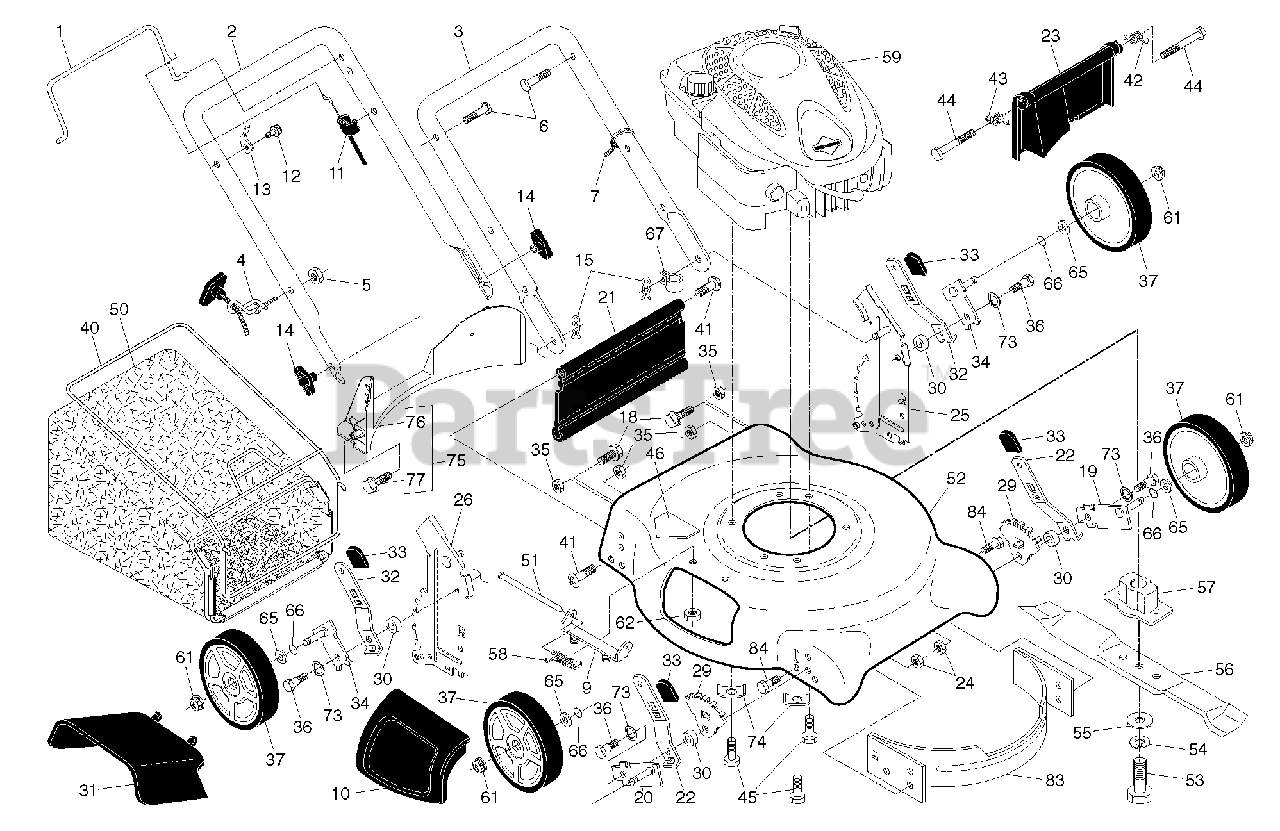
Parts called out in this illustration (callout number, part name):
1	BAIL.CONT.D.STRAIGHT.PUSH.YELL
2	HANDLE.UPPER.ECONOMY.BLACK
3	HANDLE.LOWER.D-STRAIT.BLACK
4	GUIDE.ROPE.STD.BLK.ZIN
5	NUT
6	BOLT, HANDLE 5/16-18X1.75
7	TIE GUIDE
9	BRACKET.ASM.HOUSING.EZ.MUL
10	MULCH DOOR
11	CABLE.MZR.RATO.22"LOW.
13	BRACKET.UPSTOP.RT
14	KNOB.WING.PLASTIC.BLACK
15	HAIRPIN COTTER
18	SCREW 1/4X20
19	AXLE ARM ASSY FRONT LH
20	AXLE ARM ASSY FRONT RH
21	KIT.SKIRT.21 DOMED.W/LIP
22	SELECTOR SPRING, FRONT
23	REAR DOOR ASSY
24	NUT.FLANGE.HEX.5/16X18.BLACK
25	RP BRACKET.ASM.HANDLE.LH.LW.BL
26	RP BRACKET.ASM.HANDLE.RH.LW.BL
29	WHEEL ADJ BRACKET FRONT
30	SPACER.HEIGHT.ADJUSTER
31	CLIP ON DISCHARGE GUARD
32	SPRING.SELECTOR.21RD.HTTRT.BZP
33	KNOB.ERGO.DLX.PLAS.MARI.MULTI
34	ARM.ASM.AXLE.REAR.5/9.POS.BZP
35	NUT.CENTERLOCK.5/16-
36	SHOULDER BOLT 5/16-18
37	WHEEL.12X1.75.5SPK.RAD3.BLACK
40	FRAME.BAG.21.REAR.DOMED.PUSH
41	SCREW.1/4-20X21/4.HEX.
42	SPRING.LH.22.REAR.DOOR.EZ.EMPT
43	SPRING.RH.22.REAR.DOOR.EZ.
45	BOLT 3/8-16X1-1/8
46	No Step Decal
50	GBAG.27510416S.BLK.PPR
51	ROD.HINGE.COMBI-C
53	SCREW, HEX HD 3/8-24 X 1-3/8
55	WASHER,HARDEN
56	BLADE.21.PUSH/RWGD/FWGD
57	ADAPTER.BLADE.W/KEY.25MM.CE
58	TORSION SPRING
61	NUT.HEX.FLANGE.3/8-16.LOCKNUT
62	LOCKNUT.NYLOC.1/4-20
65	WASHER PM
66	O-RING..070X.487.NEOPRENE
67	CLIP.CABLE.BLK
73	WASHER.CURVED.CYLINDRICAL
74	WASHER.ENGINE.BZP
75	KIT.BAFFLE.REAR.PLASTIC.21.RD
76	BAFFLE.REAR.PLASTIC.21.RD.ECON
77	SCREW.HX.13X.750
83	BAFFLE.FRONT.21.DOME.US
84	BOLT.5/16HEX.WHS.HD
